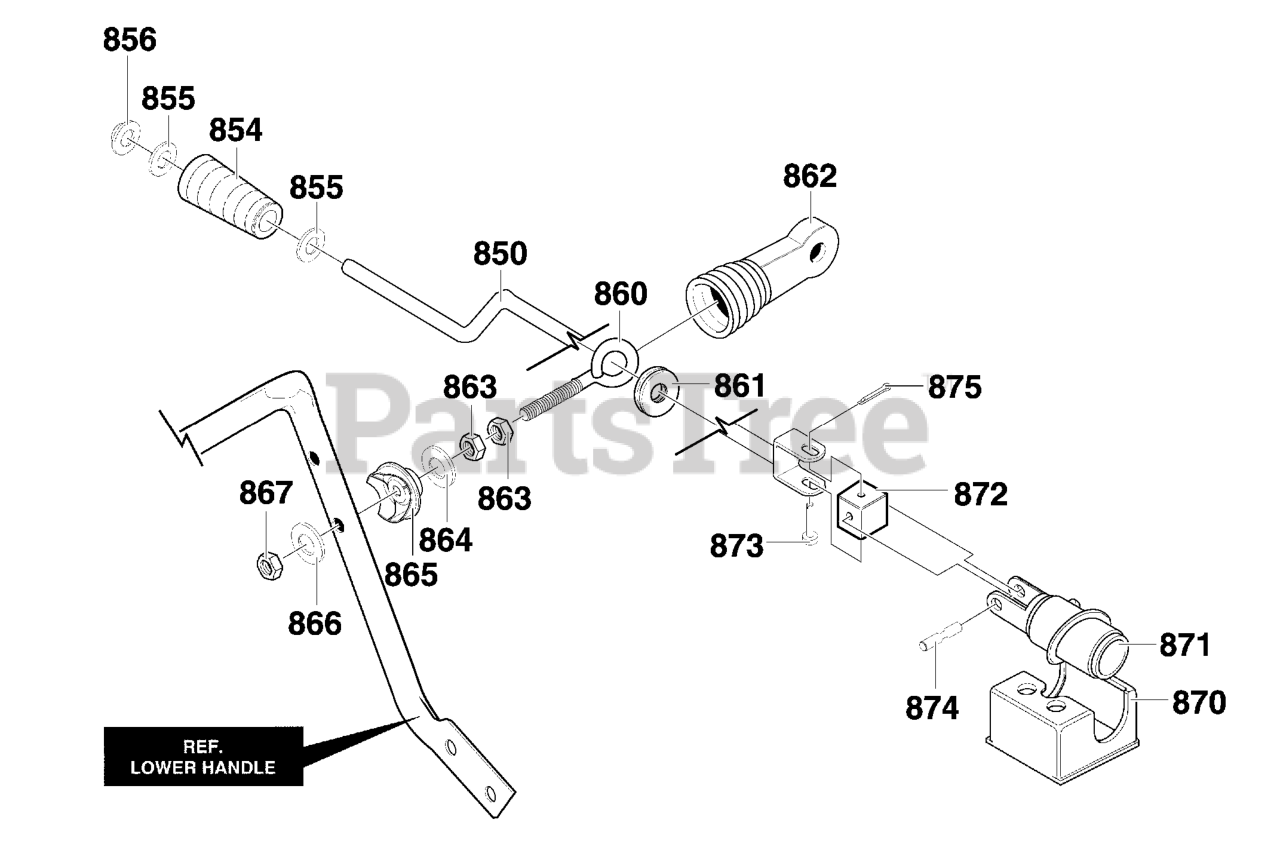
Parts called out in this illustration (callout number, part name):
850	CRANK, ASSY CHUTE
854	HANDLE, CHUTE CRANK
855	FLATWASHER .39X.70X.05
860	EYE BOLT 3/8-16X6.00
861	GROMMET, EYE BOLT
862	BOOT
863	NUT, 3/8-16 HEXJAM
864	FLATWASHER .406X.81X.066
865	ADAPTER, BOOT TO HANDLE
866	FLATWASHER .406X.81X.066
867	NUT, 3/8-16 HEXNYL
870	BRACKET, WORM MTG
871	WORM, GEAR CHUTE ROTATION
872	BLOCK, UNIVERSAL PIVOT
873	CLEVIS PIN
874	PIN, UNIVERSAL JOINT
875	COTTER PIN
